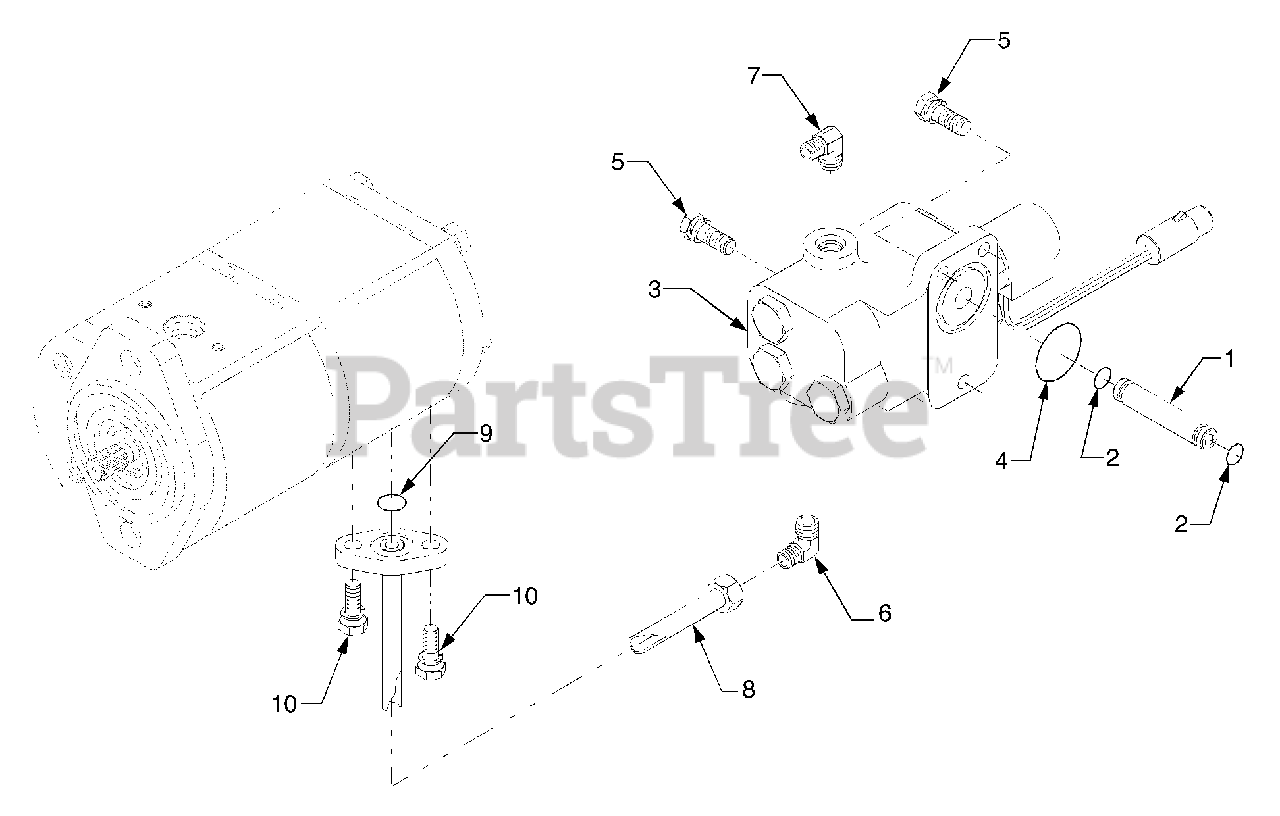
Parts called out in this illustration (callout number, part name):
1	Pipe, Connector
3	Modulater Valve Ass'y
8	Pipe, PTO Hydraulic
